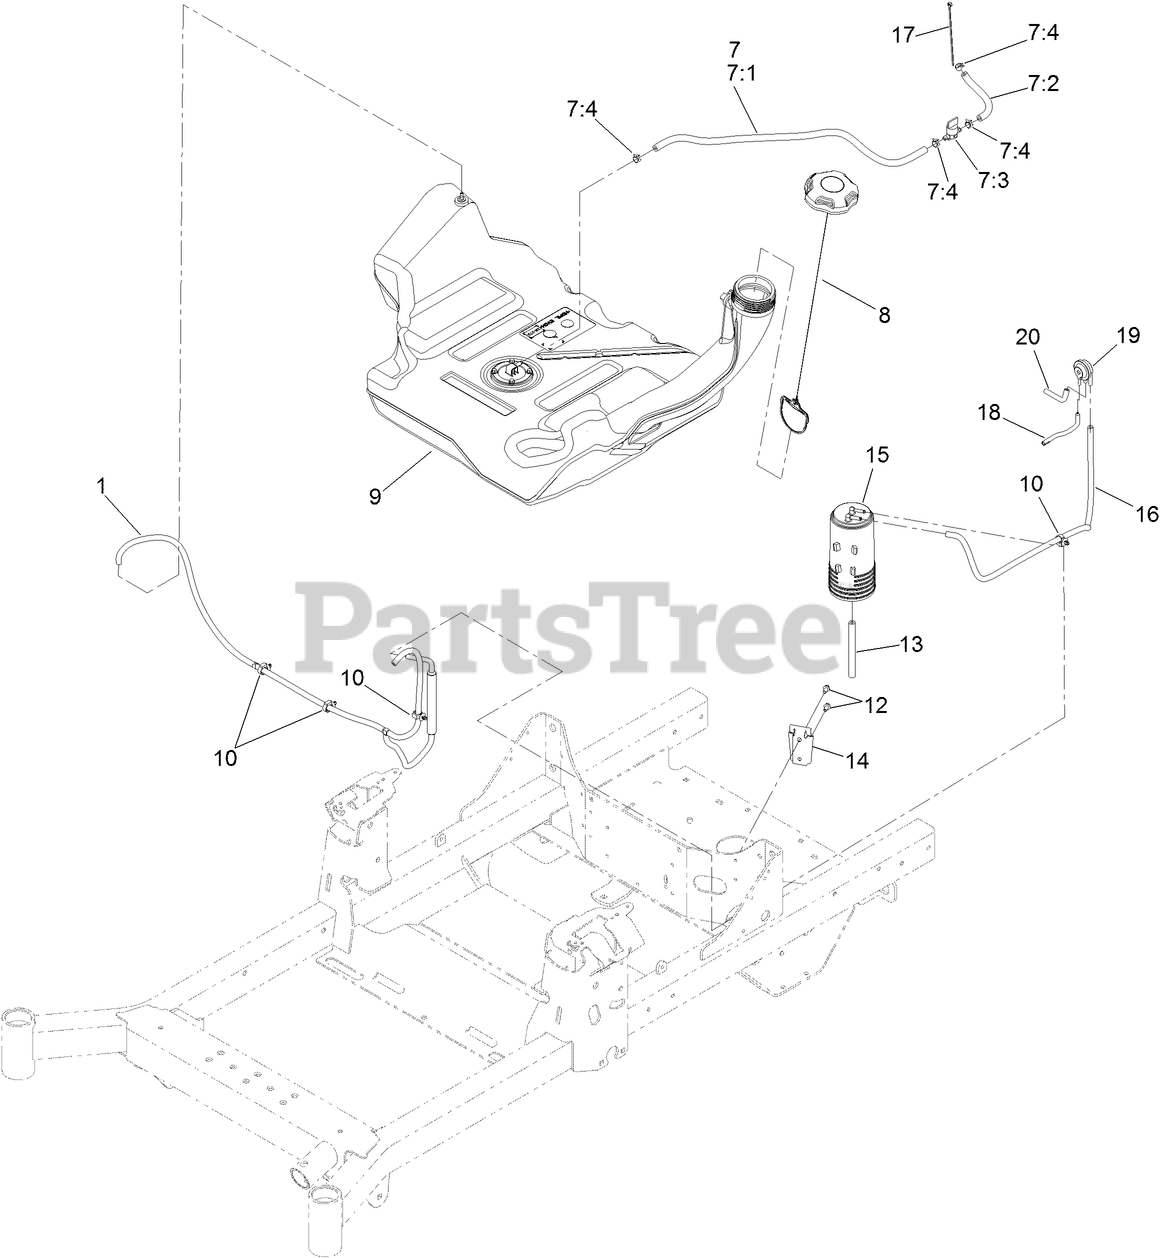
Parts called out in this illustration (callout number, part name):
1	VENT HOSE ASM
7	FUEL HOSE ASM
7:1	HOSE-FUEL
7:2	HOSE-FUEL
7:3	VALVE-FUEL
7:4	CLAMP-HOSE
8	CAP-FUEL, RATCHETING
9	TANK-FUEL
12	SCREW-HWH
13	HOSE-FUEL
14	BRACKET-CANISTER, CARBON
15	CANISTER-CARBON, 800CC
16	Hose-Fuel
17	TIE-CABLE
18	HOSE-VENT, FORMED
19	VALVE-CONTROL, VACUUM
20	HOSE-VENT, FORMED
